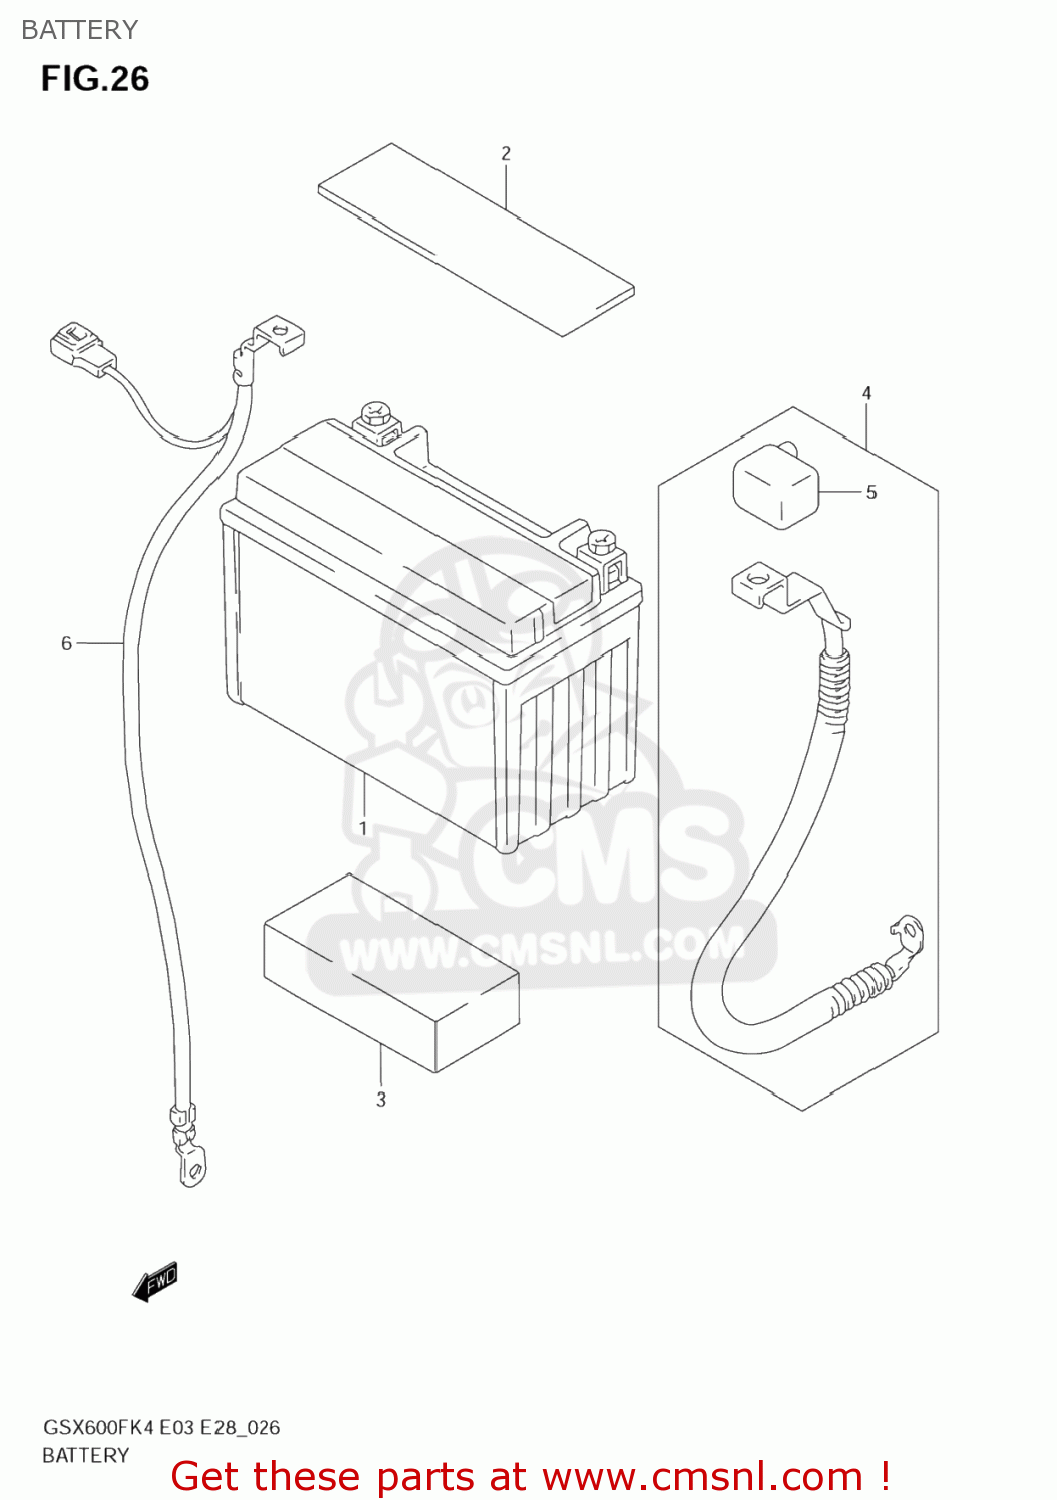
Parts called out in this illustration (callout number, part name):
1	BATTERY ASSY(YTX9-BS,12V8AH)
2	PROTECTOR(170X95X3.0)
3	PROTECTOR(20X50X8)
4	WIRE,BATTERY PLUS LEAD
5	CAP,BATTERY PLUS
6	WIRE,BATTERY MINUS
